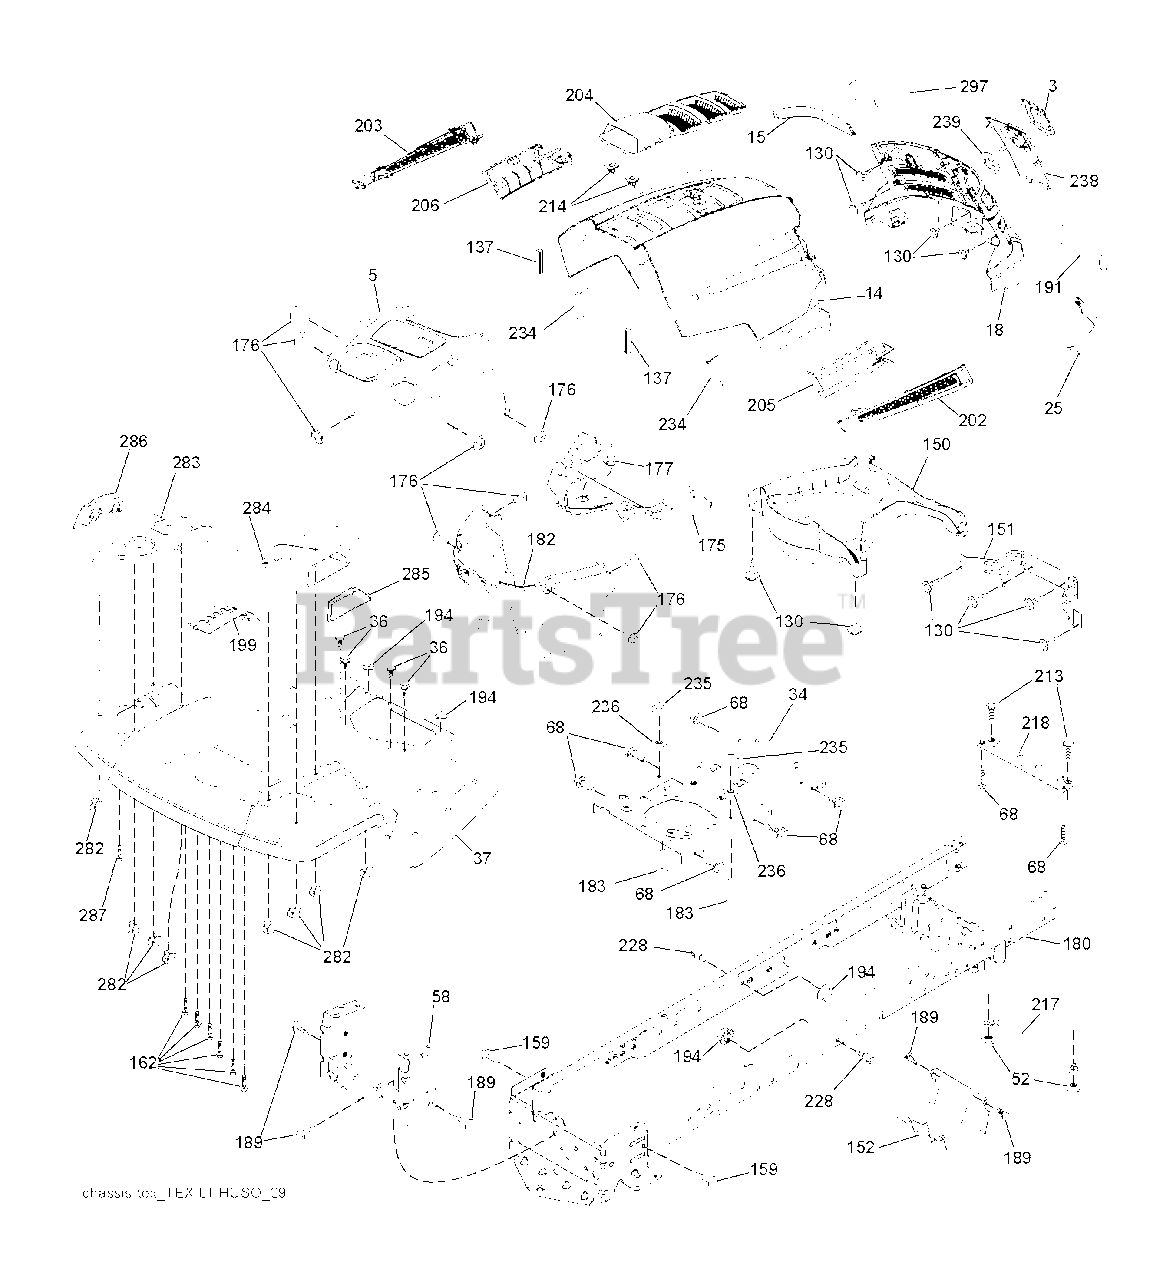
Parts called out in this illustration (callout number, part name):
3	LOGO.HUSQ.GT.LT.CROWN.H
5	SUBASM.DASH.UPPER.W/BUMPER
14	HOOD.HUSQVARNA.LT.ORANGE
15	LENS.HUSQVARNA LT.RH
18	GRILLE.SVC.HUSQVARNA.GREY
25	LENS.HUSQVARNA LT.RH
34	PLATE.ENGINE.WELDED.CHASSIS
36	SCREW 5/16"
37	FENDER.TLT.FS.W/CUPHLD.ORANGE
52	LOCKNUT
58	DRAWBAR UPPER 2PC SMALL FENDER
68	SCREW LT
130	SCREW.#10 X 0.750.BOS
137	BUMPER DASH
151	BRACKET PIVOT
152	SHIELD.BROWNING.W/TEX
159	SCREW, 3/8-16X3/4
162	SCREW.HI-LO.CONSOLE
175	CROSSMEMBER
176	SCREW.#10-24X5/8.RN.QU
177	BUSHING STEERING
180	CHASS.WLDMNT.TL.12GA/2P.48/54
182	DASH.LOWER.PREDATOR LT
183	BOLT.5/16-18X1-1/4 FULL THD
189	SCREW
191	INSERT.REFLECTIVE.RH.
194	NUT LOCK HEX FLANGE 5/16-18
199	PLATE.DECK.LIFT.HUSQ.LT
202	VENT.SIDE.HUSQVARNA.LT.RT
203	VENT.SIDE.HUSQVARNA.LT.LFT
204	SUBASM.TOP.VENT.HUSQ.LT
205	SKIRT.SIDE.HUSQVARNA.LT.RT
206	SKIRT.SIDE.HUSQVARNA.LT.LEFT
213	BOLT
214	CLIP.RETAINER.TINNER.
217	ROD.PIVOT.HOOD
218	X-PIECE.HOOD.STOP.NON/
228	STUD.FASTNER.W/ANTI-ROTATE
234	BUMPER.HOOD.TEX.HUSQVARNA
235	SPACER FENDER
236	NUT.CENTERLOCK.5/16-
238	TRIM.HUSQ LT.668
282	CLIP.RETAINER.CONSOLE.LT.HUSQ
283	CONSOLE.SHIFT.6SP.HUSQ.LT.498
284	CONSOLE.ASM.LFT.RSF.HUSQ.LT
285	CONSOLE INSERT RH
286	CONSOLE.INSRT.LH.HUSQ.LT.BLACK
287	SCREW 1/4X20
297	INSERT REFLECTIVE
